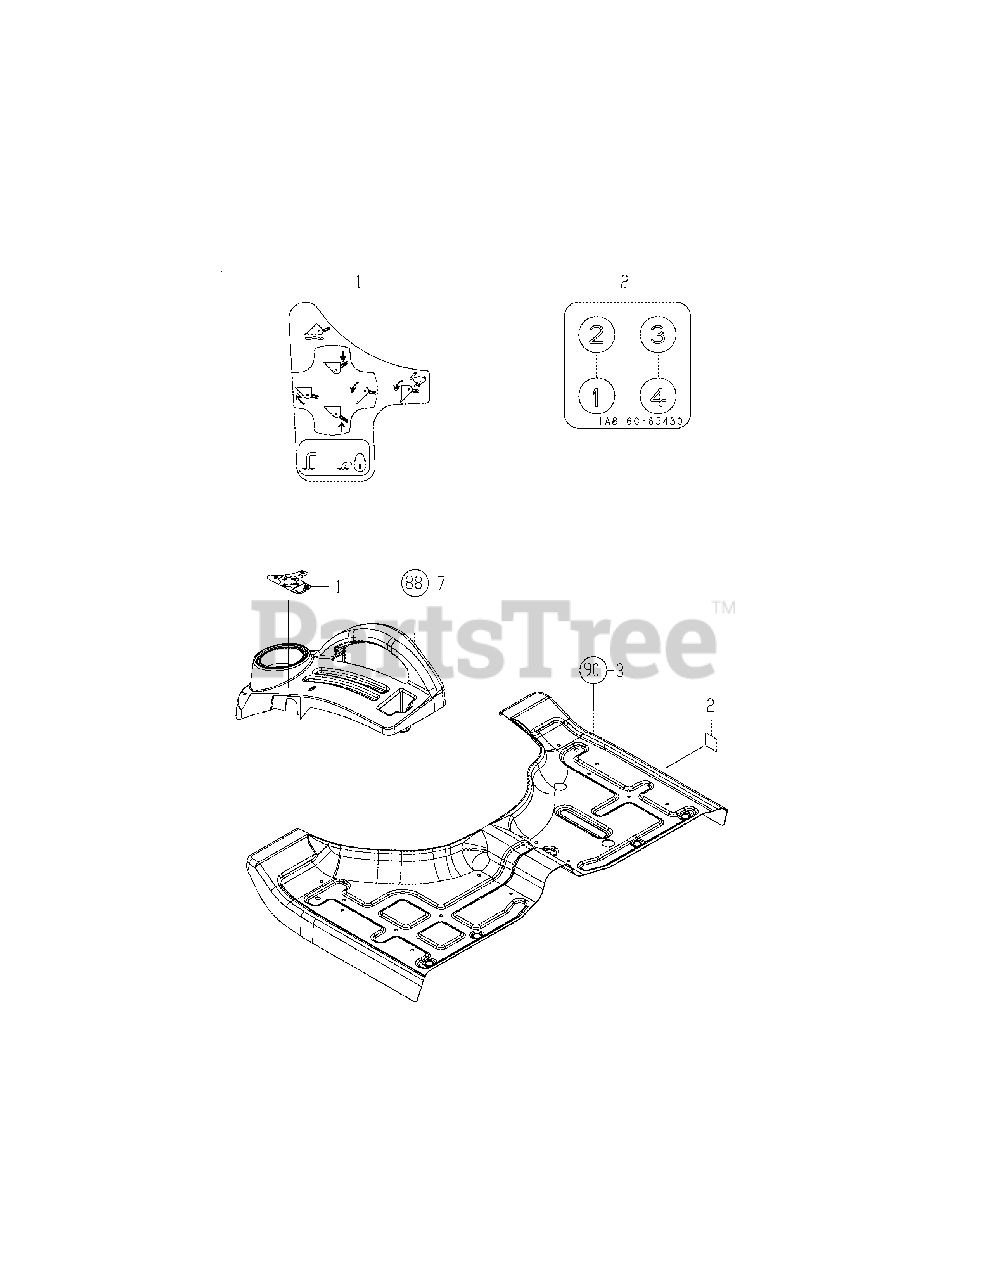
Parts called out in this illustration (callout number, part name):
1	Label, Scv Lever
1-1	Label, Scv Lever
2	Label, Scv Coupler
